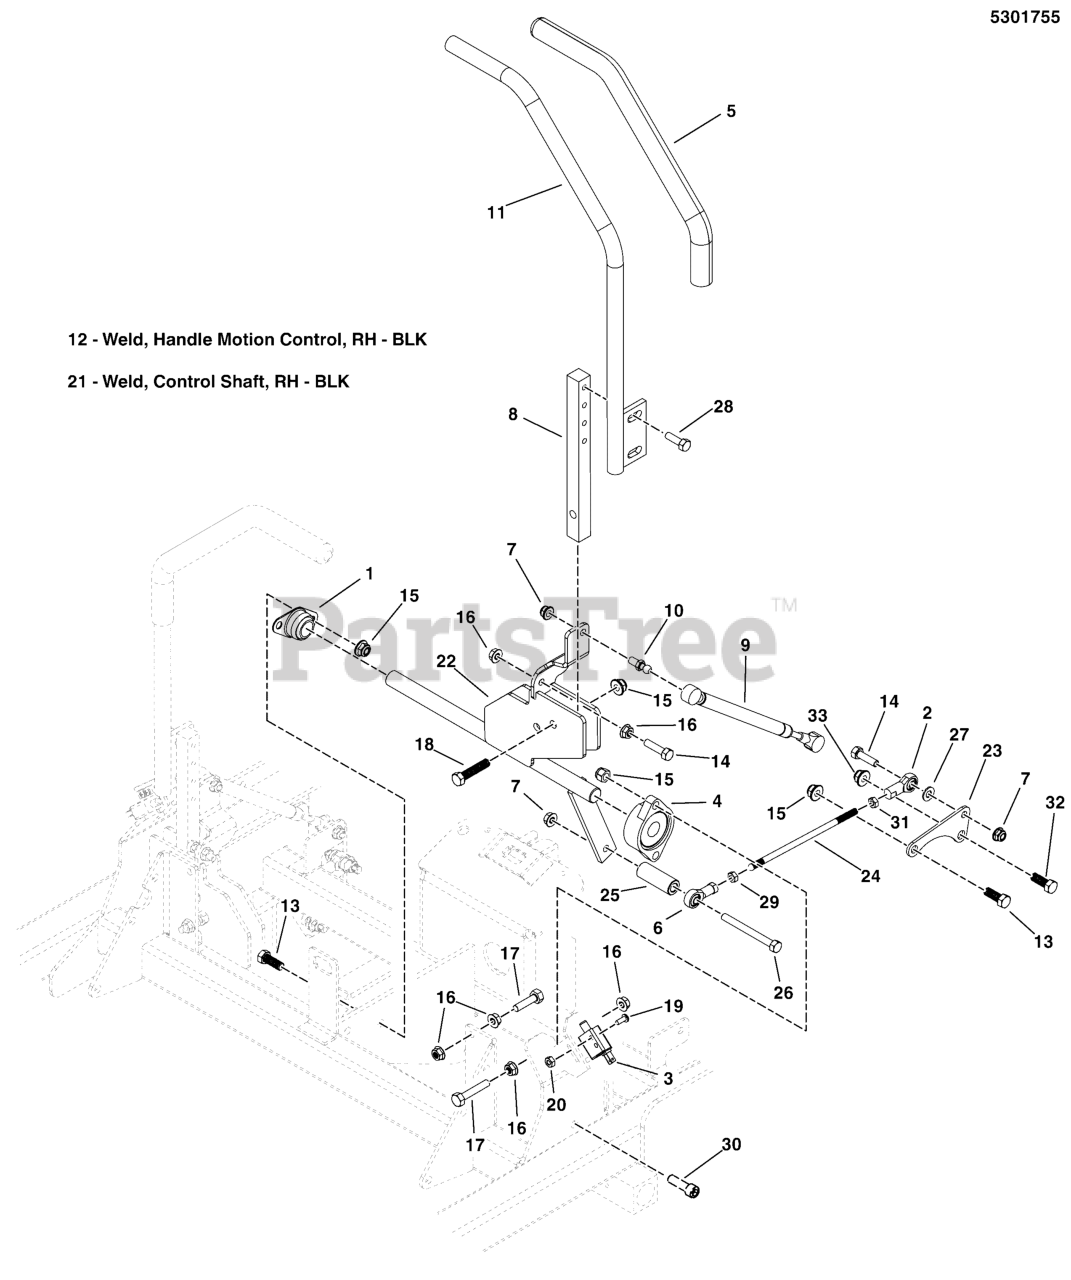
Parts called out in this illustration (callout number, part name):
1	BEARING, BRONZE FLANGE, 3/4"
2	BALL JOINT 5/16-24 RH FEMALE STAMPED STL
3	SWITCH, PLUNGER, N.O., BOLT-ON
4	BEARING, FLANGE
5	GRIP, FOAM, 3/4" ID, 16"" LONG
5	GRIP, FOAM, 1" ID, 16" LONG
6	BALL JOINT 5/16-24 LH FEMALE STAMPED STL
7	NUT, 5/16-18 HEX NYLOCK FLANGE NUT
8	MOUNT, CONTROL ARM - BLK
9	DAMPENER, CONTROL,#(P6709/P3610)
10	BALL STUD, 5/16 X .50,# PC-477-2)
11	WELD, HANDLE MOTION CONTROL LH - BLK
11	WELD, HANDLE MOTION CNTRL, 19.0, 1.0, LH - BLK
13	BOLT, 3/8-16 X 1" GD5 CZ
14	BOLT, 5/16-18 X 1-1/4" GD5 YZ
15	NUT, 3/8-16 HEX NYLON LOCK
16	NUT, 5/16-18 HEX SERRATED FLANGE (SMALL)
17	BOLT, 5/16-18 X 1-3/4 TFL, GD5 YZ
18	BOLT, 3/8-16 X 1-3/4" GD5 CZ
19	SCREW, #10-24 X 1/2" ROUND PHILLIPS
20	NUT, HEX, #10-24
22	WELD, CONTROL SHAFT, LH - S200XT- BLK
23	PLATE, HYDRO CONNECTOR, S200XT - BLK
24	ROD, HYDRO LINKAGE - S200XT - YZ
25	SPACER, .38 X .75 X 1.25, YZ
26	BOLT, 5/16-18 X 2-1/2" GD5 YZ
27	WASHER, 5/16" SAE
28	SCREW, 5/16-18x0.750, GR5, WHIZ-LOCK, ZC
29	NUT, Hex, 5/16-24
30	BOLT, Allen Head, 3/8-16 x 1-1/4
31	NUT, 5/16-24 HEX, LH
32	BOLT, 7/16-14 X 3/4, GD 5 YZ
33	NUT, 7/16-14 HEX TOP LOCK
